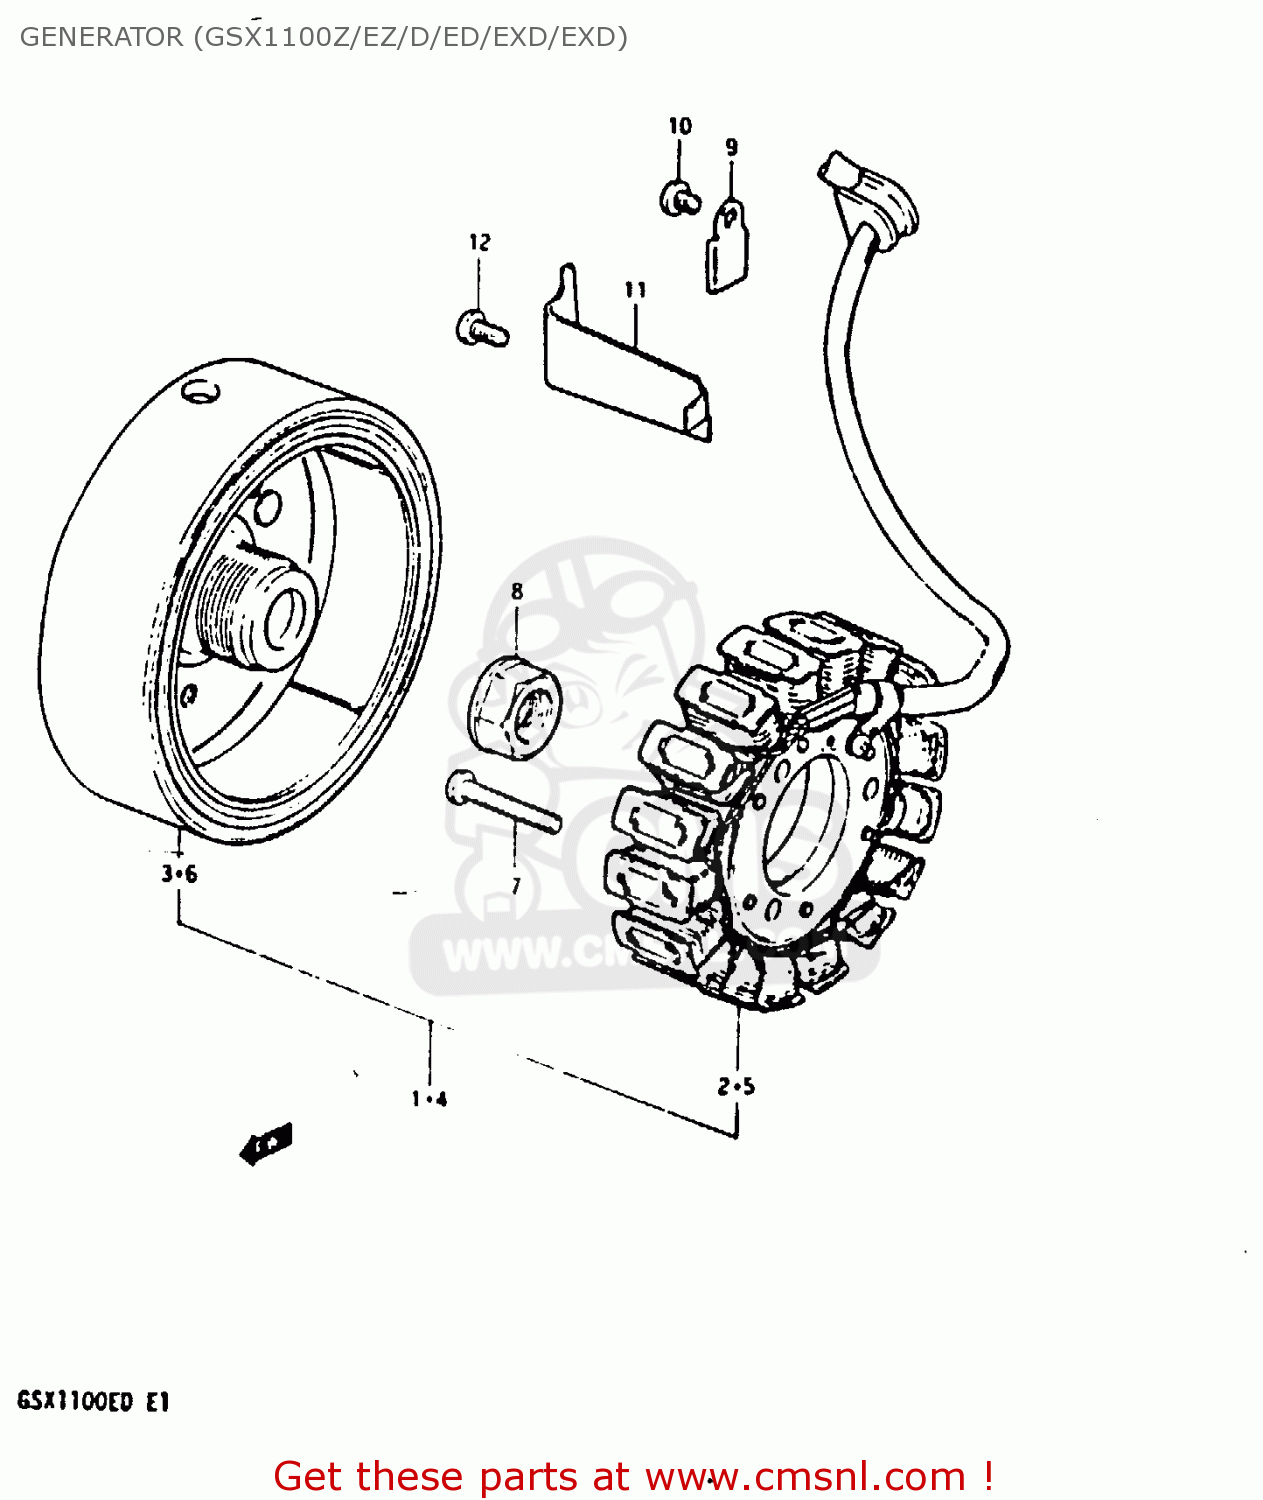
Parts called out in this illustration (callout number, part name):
1	GENERATOR ASSEMBLY
2	STATOR ASSEMBLY
3	ROTOR ASSY
4	GENERATOR ASSEMBLY
5	STATOR ASSEMBLY
6	ROTOR ASSEMBLY
7	SCREW 6X30
8	NUT,GENERATOR ROTOR
9	CLAMP,GENERATOR LEAD WIRE
10	SCREW
11	CLAMP,GENERATOR LEAD WIRE
12	SCREW
